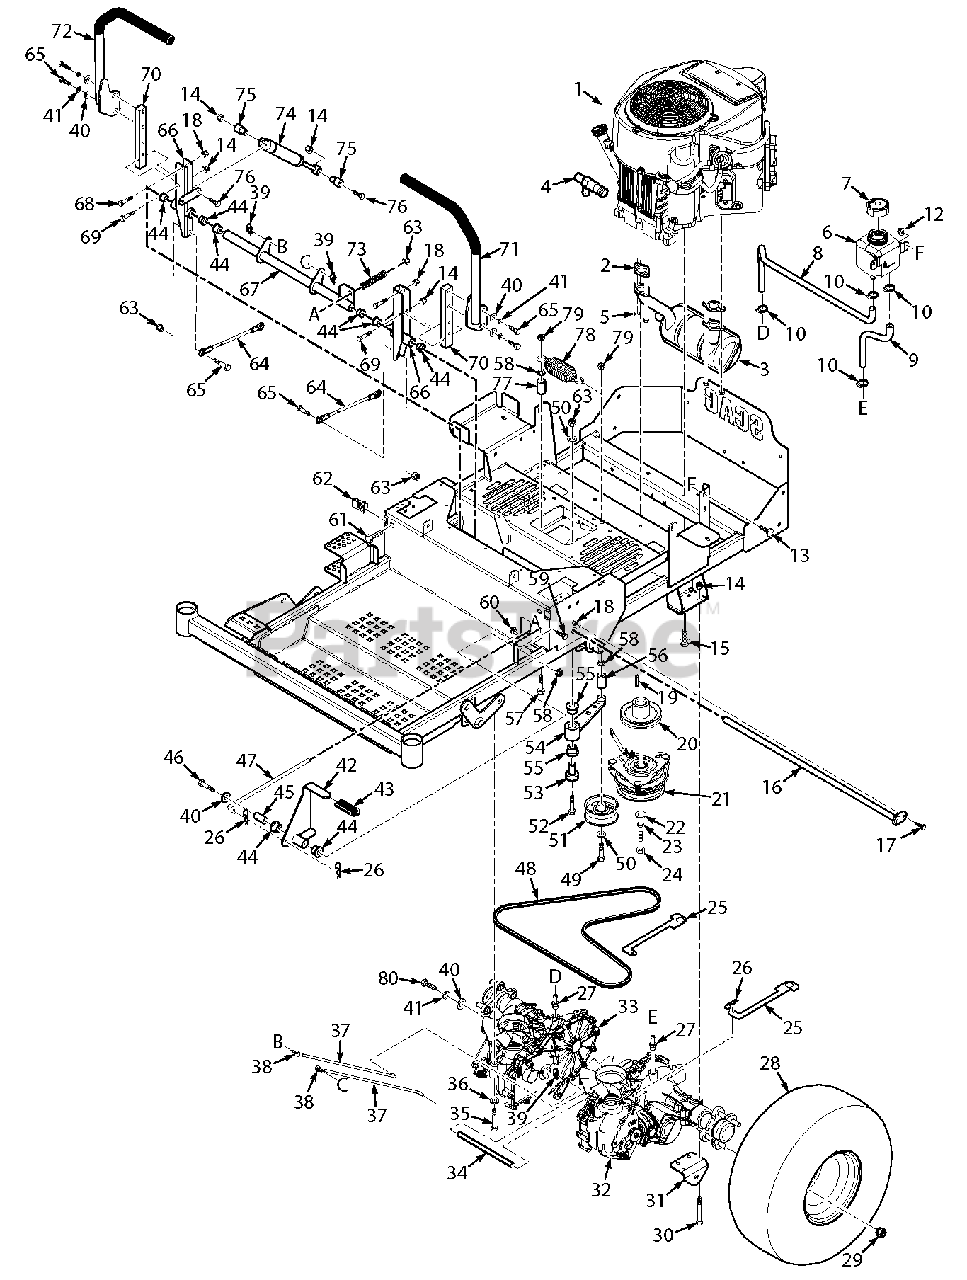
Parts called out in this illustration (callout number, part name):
1	Engine, Kawasaki - FR651V
1	Engine, Kawasaki - FR691V
2	Gasket, Exhaust
3	Muffler, Kawasaki FR651V & FR691V
4	Oil Drain, Kawasaki
5	Nut, M6-1.0 Hex Flange
6	Reservoir Assembly
8	Hose, RH Transmission
9	Hose, LH Transmission
10	Clamp, .87 Max. Dia.
11	Clamp, .69 Max. Dia.
12	Nut, 1/4-20 Flange Elastic Stop
13	Bolt, Carriage 1/4-20 x 3/4"
14	Nut, 5/16-18 Elastic Stop
15	Bolt, 3/8-16 x 1-1/4" Serrated Flange Self Tap
16	Shaft Weldment, Control Arm
17	Bolt, Hex Head 1/4-20 x 5/8"
18	Nut, 1/4-20 Elastic Stop
19	Key, 1/4 x 1/4 x 1-1/4"
20	Pulley, 4-1/2" - 1" Bore
21	Clutch, GT1
22	Flatwasher, 7/16-.496 x 1.75 x .25
23	Lockwasher, 7/16"
24	Bolt, 7/16-20 x 3" w/Patch
25	Lever, Dump Valve
26	Hair Pin Cotter, .080 x 1.19
27	Fitting, O-Ring x 3/8" Hose
28	Wheel Assembly
28	Rim w/Valve Stem
28	Tire, 20 x 10-8
29	Wheel Nut, 1/2-20 x 13/16
30	Bolt, Hex Head 5/16-18 x 3"
31	Bracket, Pusharm
32	Transaxle, LH - SZL
33	Transaxle, RH - SZL
34	Spacer
35	Bolt, Hex Head 5/16-18 x 2-1/4"
36	Flatwasher, 5/16-.375 x .875 x .083
37	Rod, Brake
38	Joint, Swivel
39	Pin, Rue Cotter - 3/8"
40	Flatwasher, 3/8-.391 x .938 x .105
41	Lockwasher, 3/8"
42	Brake Lever Assembly
43	Grip, Brake Handle
44	Bearing
45	Pivot, Brake Lever
46	Bolt, Hex Head 3/8-16 x 2-1/2"
47	Rod, Upper Brake Linkage
48	Belt, Transmission-SZL
49	Bolt, Hex Head 3/8-16 x 3-3/4"
50	Flatwasher, 3/8-.391 x .938 x .105 HD
51	Pulley, 3-1/2" Idler
52	Bolt, Hex Head 3/8-16 x 3"
53	Shaft, Pivot Idler Arm
54	Idler Arm Assembly
55	Bearing
56	Spacer, Pump Idler
57	Bolt, Hex Head 3/816 x 2"
58	Nut, 3/8-16 Serrated Flange
59	Bolt, Hex Head 1/4-20 x 1"
60	Nut, 1/4-20 Serrated Flange
61	Bolt, Hex Head 3/8-16 x 2-1/2" Special Lock
62	U-Nut, 3/8-16
63	Nut, 3/8-16 Elastic Stop
64	Linkage, Pump
65	Bolt, Hex Head 3/8-16 x 1-1/4"
66	Control Arm Assembly
67	Bellcrank Assembly
68	Bolt, Hex Head 1/4-20 x 1-3/4"
69	Bolt, Hex Head 5/16-18 x 1-3/4"
70	Bar, Control Lever
71	Handlebar w/Grip
71	Grip, Control Lever
72	Handlebar w/Grip
72	Grip, Control Lever
73	Spring, Brake
74	Damper, Steering
75	Spacer, Damper
76	Bolt, Hex Head 5/16-18
77	Spacer
78	Spring, Transmission Drive
79	Nut, 3/8-16 Center Lock
80	Bolt, Hex Head 1/4-20 x 1-1/2
